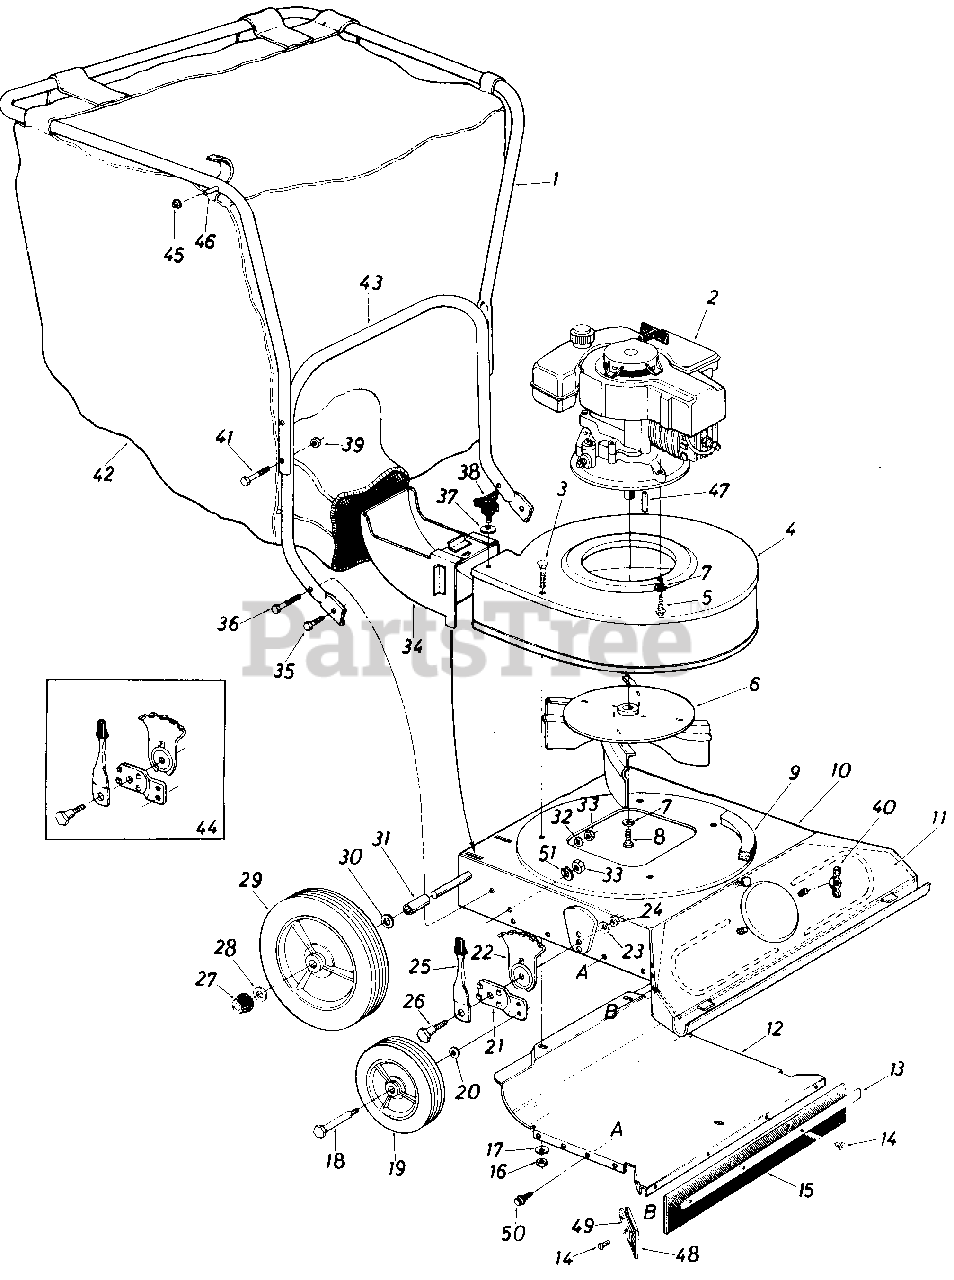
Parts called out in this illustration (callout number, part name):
1	Upper Handle (Painted)
2	Engine
3	Carriage Bolt 5/16-18 x .62" Lg.*
4	Blower Housing Ass'y.
5	Hex Tap Scr. 3/8-16 x 1.00" Lg.
6	Impeller Ass'y.
7	L.-Wash. 3/8" I.D.*
8	Hex Bolt 3/8-24 x 1.0" Lg. w/ Patch
9	P.V.C. Foam Strip (4-Pcs. 12" Lg.)
10	Vacuum Deck Ass'y.
11	Front Baffle Ass'y.
12	Lower Baffle Ass'y.
13	Wiper Retaining Strip
14	Pop Rivet.188" Dia.
15	Nozzle Wiper Rear
16	Hex Nut 5/16-18 Thd.*
17	Bel l.-Wash. .34" I.D. x .87" O.D.
18	Shld. Bolt 1/2" Dia. x 1.45" Lg. (3/8-16)
19	Wheel Ass'y. Comp. 8 x 1.75"-Front
20	Bell.-Wash. .39" I.D. x 1.12" O.D.
21	Wheel Pivot Bar
22	Index Plate
23	Bell.-Wash. .39" I.D. x 1.12"O.D.
24	Hex Nut 3/8-1 Thd.*
25	Spring Lever Ass'y. w/Knob
26	Shoulder Bolt .500" x 7/16" Lg. (3/8-16)
27	Push Cap .50" Rod (Black)
28	Fl.-Wash. 1/2" I.D. x 1.0" O.D. x .06
29	Wheel Ass'y. Comp. 10 x 1.75"-Rear
30	Fl.-Wash. 1/2" I.D. x 1.0" O.D. x .06
31	Wheel Spacer 1/2" I.D. x 15/16" Lg.
32	Bell.-Wash. .39" I.D. x 1.12"O.D.
33	Hex Nut 3/8-16 Thd.*
34	Air Duct Ass'y.
35	Hex Bolt 3/8-16x.75" Lg.*
36	Hex Bolt 3/8-16 x 1.50" Lg.*
37	Bell.-Wash. .34" I.D. x.87" O.D.
38	ThumbScr. 5/16-18x.75" Lg.
39	Hex Cent. L.-Nut 1/4-2 Thd.
40	Wing Nut 1/4-20 (Plastic)
41	Hex Bolt 1/4-20 x 1.75" Lg.*
42	Vacuum Bag (6.6 Bushel)
43	Lower Handle (Painted)
44	Height Adjuster Ass'y. Comp.-R.H.
45	Push Speed Nut .25" Dia.
46	Stud Pin .250" Dia. x 1.75" Lg.
47	Sq. Key 3/16 x 3/16 x l.OO"Lg
48	Nozzle Wiper Side
49	Wiper Retaining Strip
50	HexWash. Hd. "F" TapScr. #10
51	L-Wash. 3/8" I.D.*
